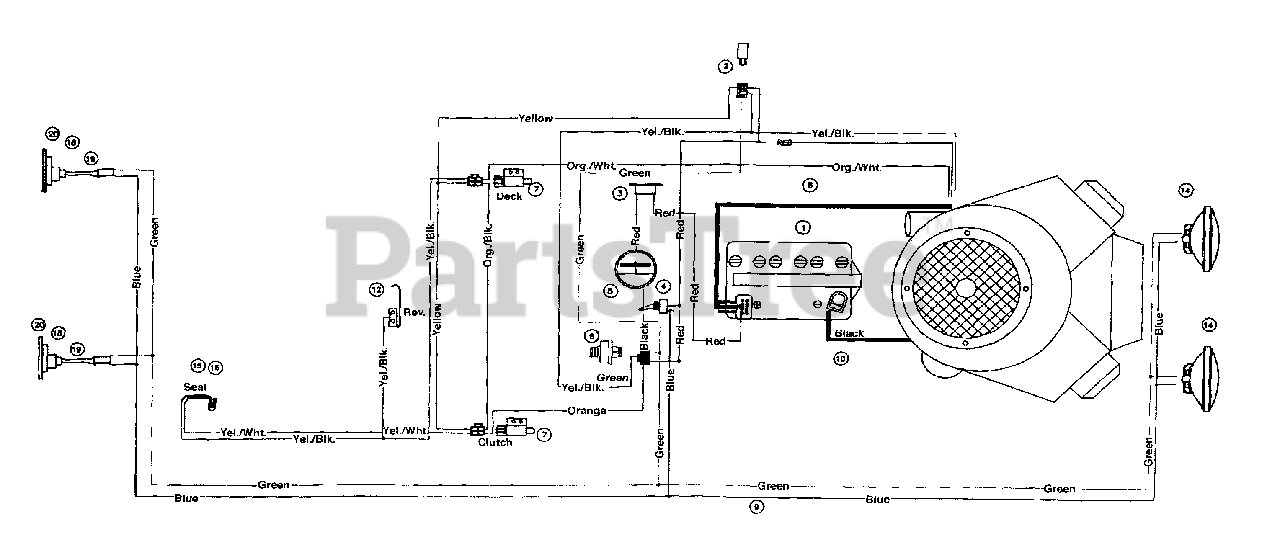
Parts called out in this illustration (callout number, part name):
1	Battery
2	Bosch Relay
5	Ammeter
6	Ignition Switch
7	Interlock Switch
8	Wire 6 Gage Red 32.5" Lg.
9	Harness
12	Reverse Safety Switch
14	Bulb, Headlight
15	Seat Safety Switch
18	Tail Light
19	Tail Light Harness
20	Bulb, Tail Light
